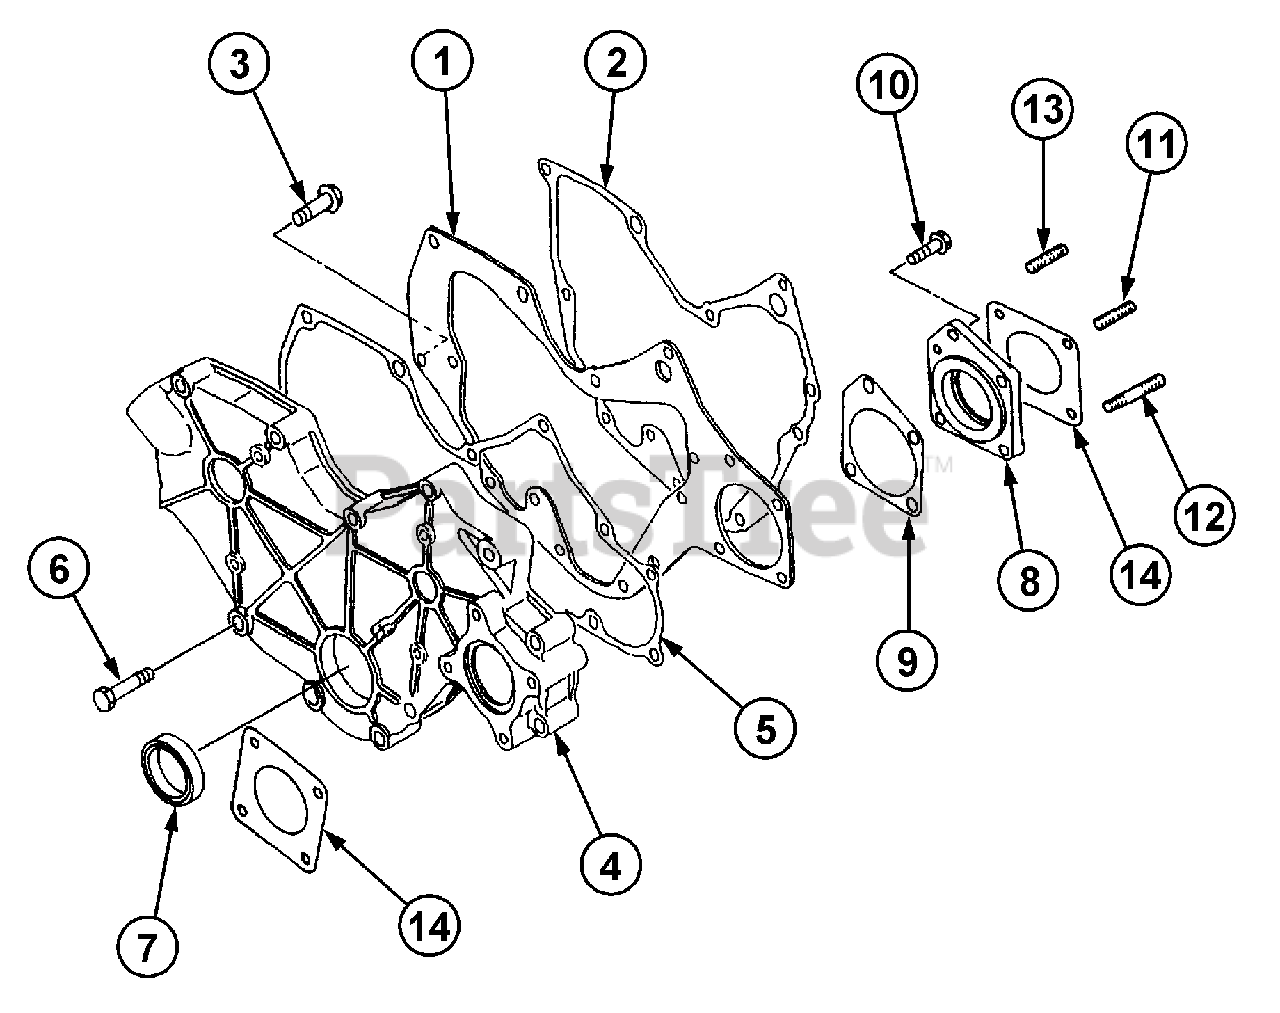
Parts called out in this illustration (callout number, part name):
2	Gasket, Plate
3	Bolt, w/Washer
4	Gear Case, P.T.O.
5	Gasket, Gearcase
8	Housing, Gearpump
9	Gasket, Housing
10	Bolt, w/Washer
11	Stud (8x25)
12	Stud (8x45)
13	Stud (8x22)
14	Gasket, Cover
